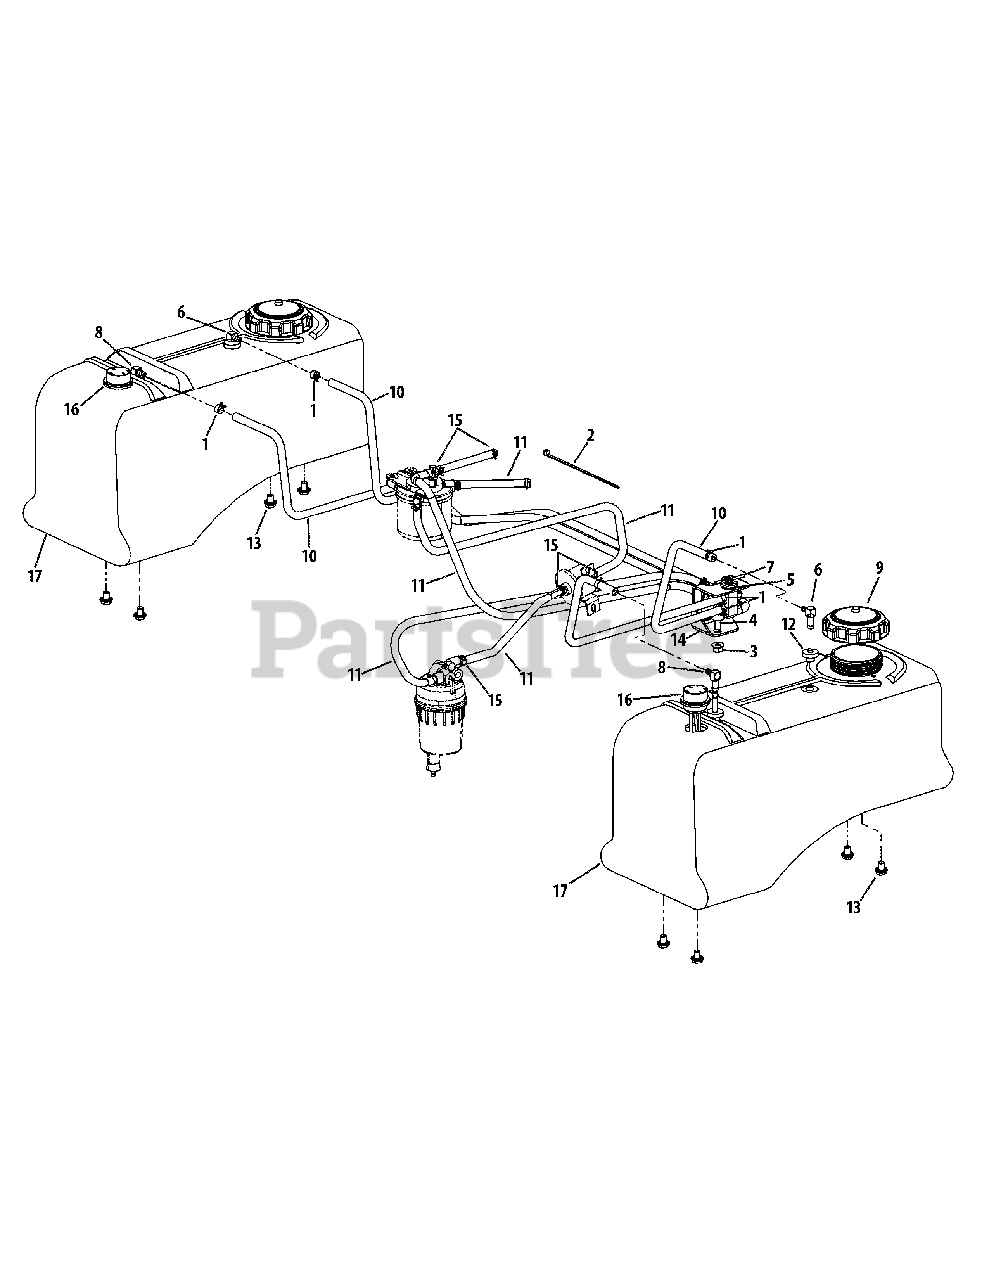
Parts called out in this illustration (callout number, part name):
1	Hose Clamp
2	Cable Tie
3	Flange Counter Lock Nut, 3/8-16
4	Carriage Bolt, 3/8-16 x .75
5	Washer, .675 x 1.05 x .048
6	Fuel Tank Elbow, 1/4
7	Fuel Valve
8	Fuel Pick-Up Fitting Valve
9	Diesel Fuel Cap
10	Fuel Hose, 1/4
11	Fuel Hose, 5/16
12	Fuel Tank Grommet
13	Hex Flange Screw, 3/8-16 x .500
14	Fuel Valve Bracket
15	Hose Clamp
16	Fuel Gauge
17	Fuel Tank w/ Gauge
